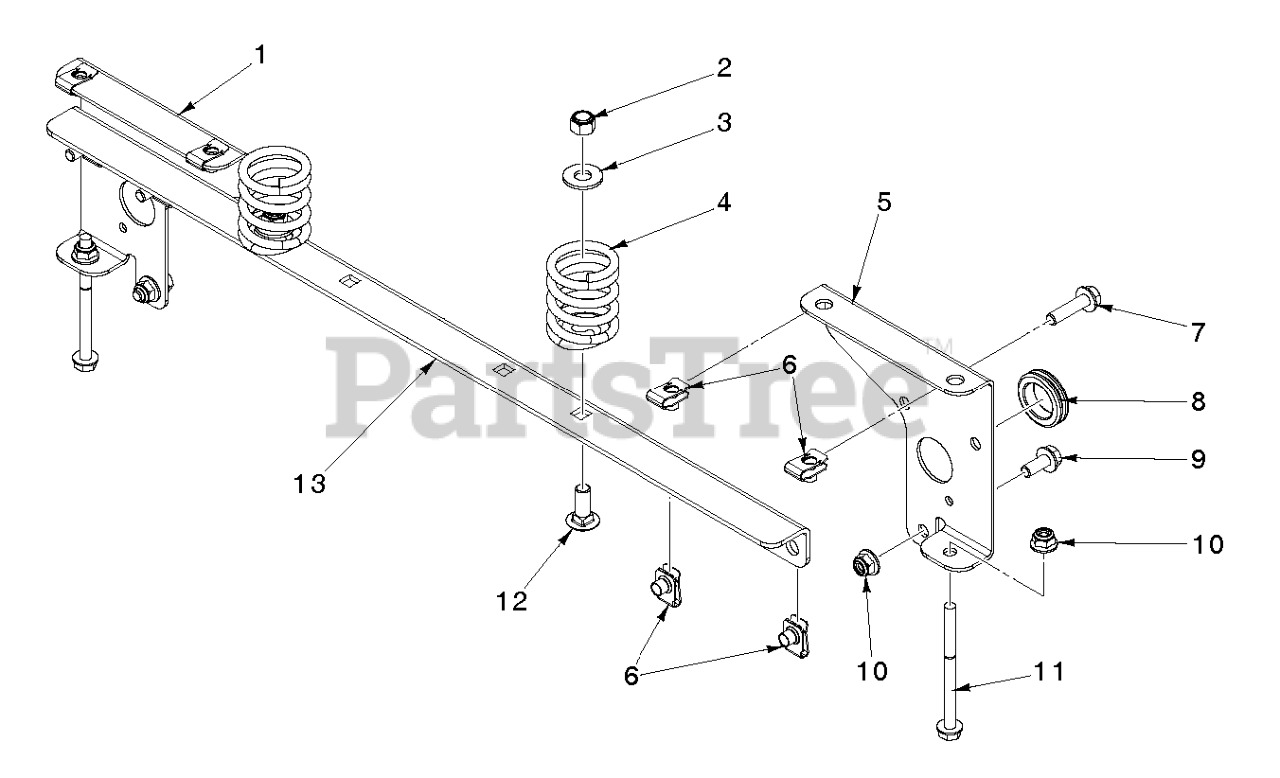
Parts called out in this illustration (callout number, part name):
1	SUPPORT.RT.BLK
3	GSPW Washers
4	SPRING.COMPRESSION.SEAT.BLACK
5	SUPPORT.LT.BLK
6	U-CLIP 5/16-18 NUT RETAINER
8	RUBBER GROMMET
10	NUT HEXAGON FLANGE 5/16-18 ST
11	BOLT.HEX.FLNG.5/16-18X3.75
